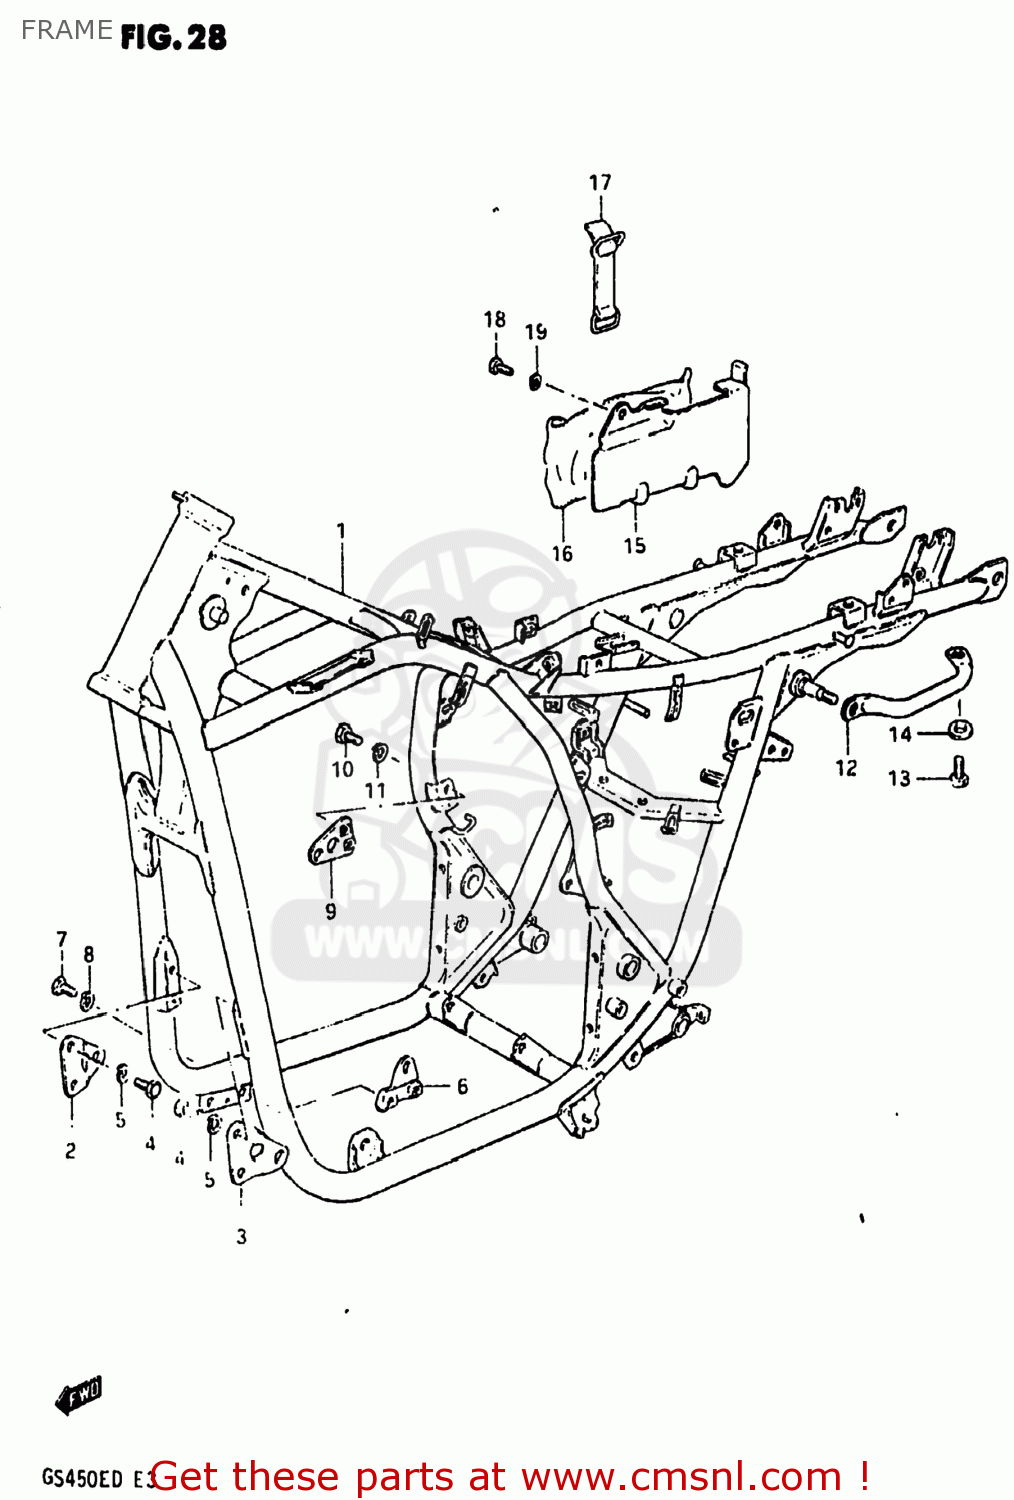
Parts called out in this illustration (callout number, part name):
1	FRAME
2	PLATE,ENG MTG NO.1,R
3	PLATE,ENGINE MOUNTING,LEFT
4	BOLT
5	LOCK WASHER
6	PLATE,MOUNTING NO.2,LEFT
7	BOLT
8	LOCK WASHER
9	PLATE,MOUNTING NO.4,LEFT
10	BOLT
11	LOCK WASHER
12	GRIP,FRAME HANDLE
13	BOLT
14	WASHER
15	HOLDER,TOOL
16	TOOL SET
17	BAND
18	BOLT
19	LOCK WASHER
